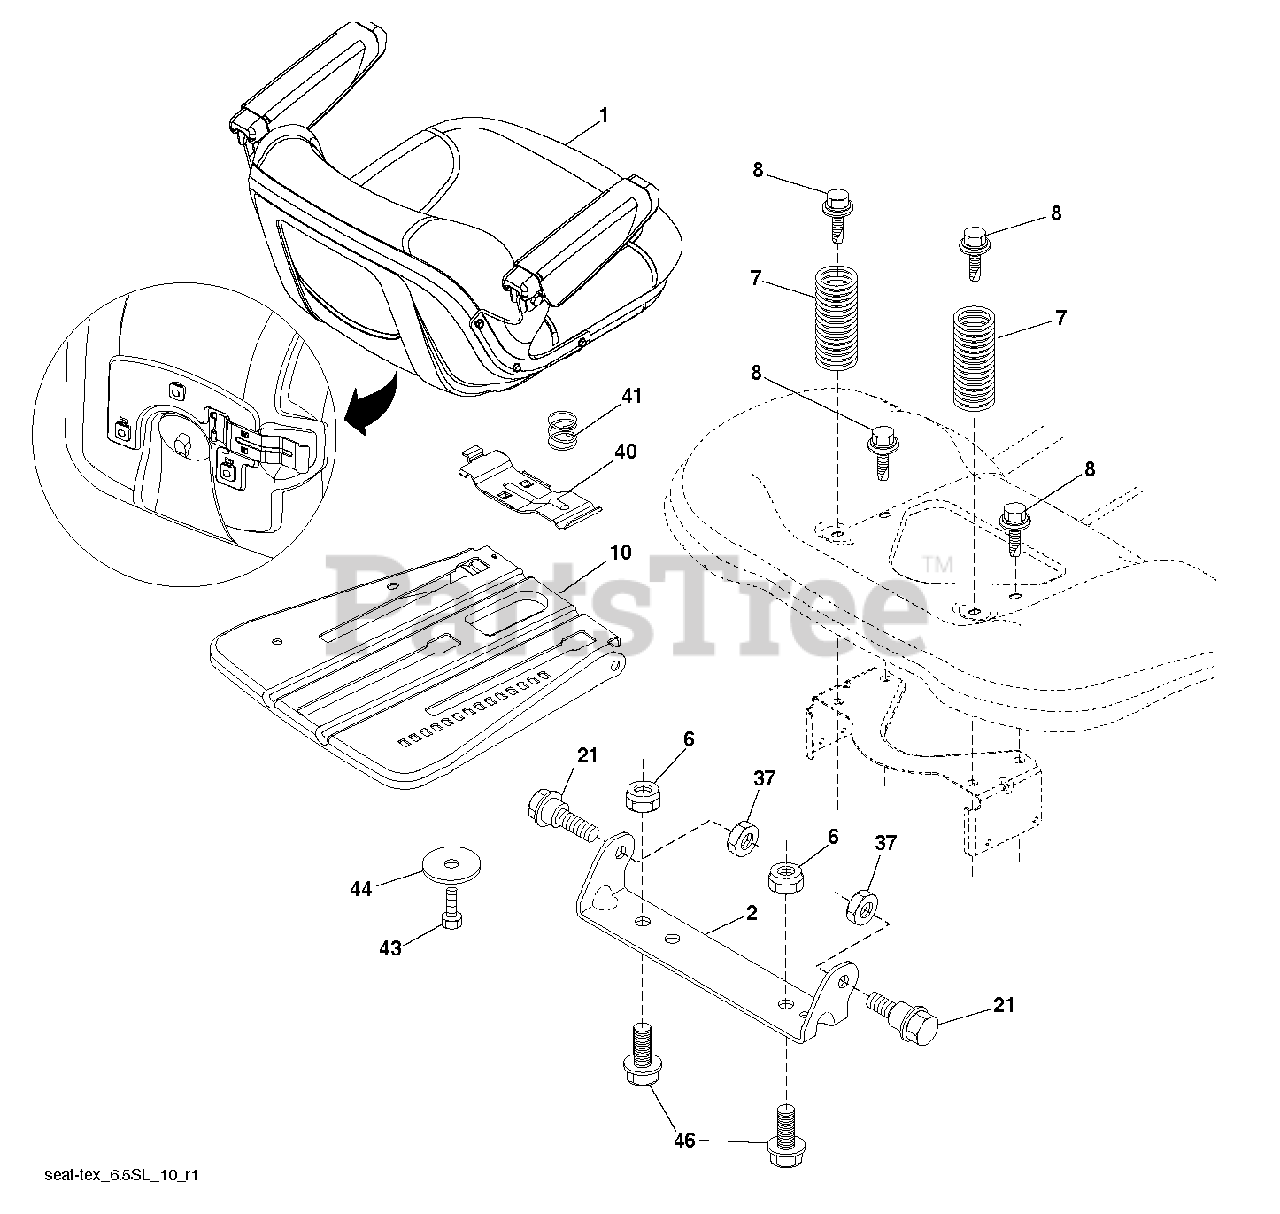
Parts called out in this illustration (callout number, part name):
1	SEAT.TH154.GREY.HUS.ARMREST
2	BRKT.PIVOT.FENDER
6	NUT
7	SPRING.COMPRESSION.SEAT.BLACK
8	BOLT, 5/16-18 X 1 3/4
10	PAN.ASM.SEAT.3PT
21	BOLT.5/16-18X5/8.SHOULDER
37	NUT.71038.31-18.HEX.NYLOCK
40	HANDLE.SLIDE.SEAT.TEX.GREY
41	SPRING.LATCH.SEAT.TEX
44	WASHER 13/32 X 2-3/8 X 12GA
46	BOLT.3/8-16X1;1.25OD.WSHR.SEMS
